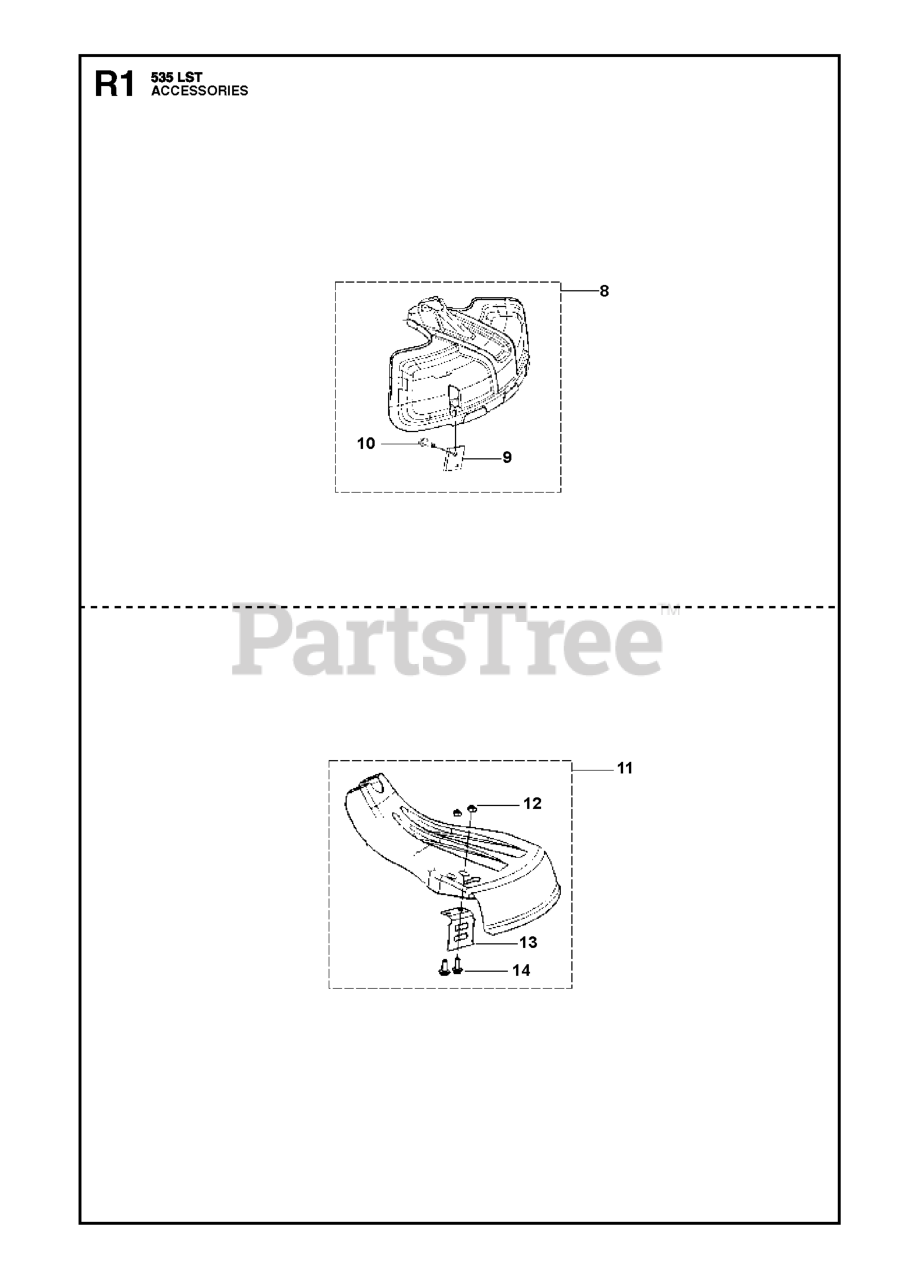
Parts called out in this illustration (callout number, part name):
8	COMBINATION GUARD
9	LINE CUTTER
10	SCREW ITXSCFT PW4.8X16 T27 CH
11	GUARD ASSY
